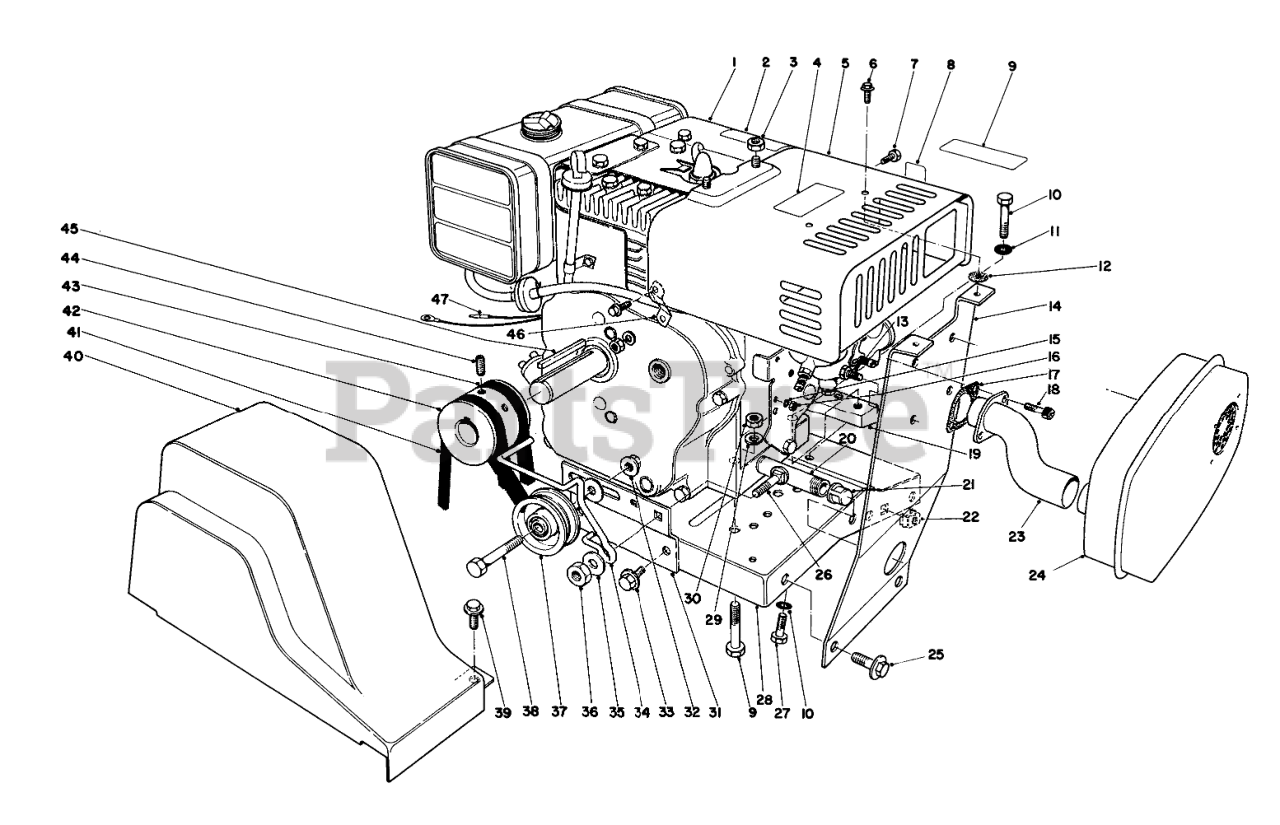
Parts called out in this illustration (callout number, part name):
1	Engine
3	NUT-HEX, SIDE DEFORM
4	Decal
5	Heater Box
6	SCREW
8	Decal-Choke
9	Decal-Syncro Balance
10	SCREW-HH
11	WASHER-LOCK, INTERNAL
12	Washer
13	1/4-20 X 1/2 SEMS MS
14	Muffler Mounting Bracket
15	WASHER-LOCK/INT
16	NUT-LOCK
17	Gasket
18	SCREW-HSH
19	Block Engine Mounting
20	NIPPLE-PIPE
21	CAP-PIPE
22	Retained Nut
23	EXHAUST PIPE
24	Muffler
25	SCREW-HH
26	SCREW-CARR
27	SCREW-HH
28	Base-Engine
29	WASHER-PLAIN
30	NUT-LOCK, NI
31	BELT IDLER BRKT
32	NUT-HHF, WHIZ
33	SCREW-HHFTF
34	BELT GUIDE
35	WASHER-FLAT
36	NUT-HEX
37	PULLEY B
38	SCREW-HH
39	SCREW-HWH
40	BELT GUARD
41	V-BELT
42	ENGINE PULLEY
43	V-BELT
44	Screw-Set
46	Brace Heater Box
